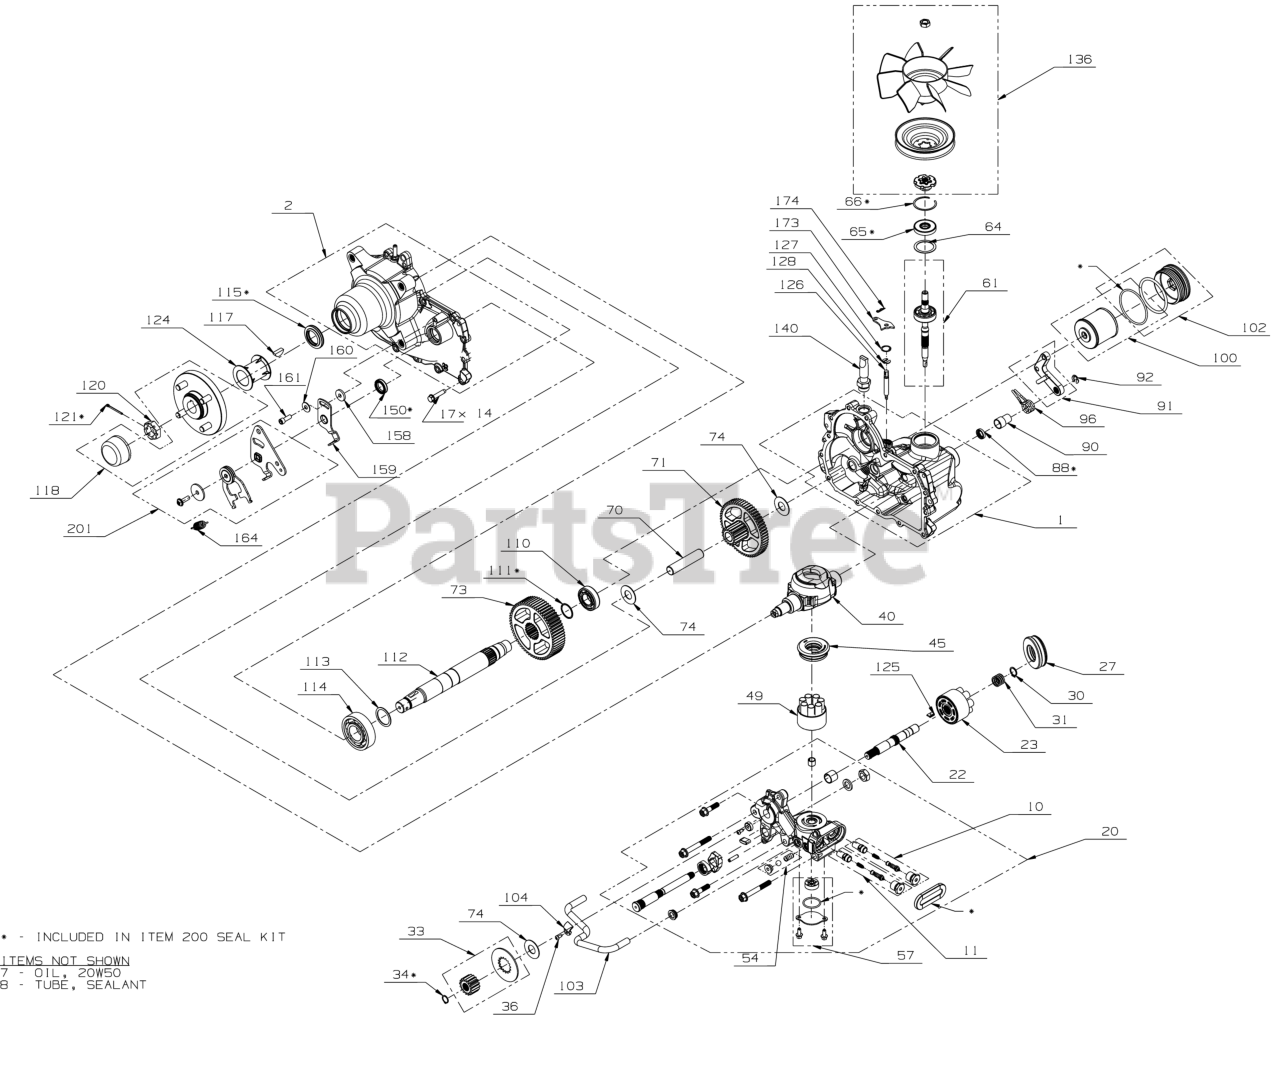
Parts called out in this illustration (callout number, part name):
1	MAIN HOUSING (RH) KIT
2	SIDE HOUSING (RH) KIT
8	SEALANT-HOUSING
10	SHOCK VALVE KIT
11	SHOCK VALVE KIT
17	HOUSING SCREW
20	CENTER SECTION (RH) KIT
22	MOTOR SHAFT
23	16CC CYLINDER BLOCK KIT
27	THRUST BEARING
30	RETAINING RING
31	SPRING-BLOCK
33	BRAKE ROTOR GEAR KIT
34	RETAINING RING
36	SCREW-SELF TAPPING
40	16CC MACHINED SWASHPLATE
45	THRUST BEARING
49	BLOCK KIT-CYLINDER
54	CHARGE RELIEF KIT
57	CHARGE PUMP KIT
61	INPUT SHAFT KIT
65	LIP SEAL
66	INTERNAL RETAINING RING 1.875
70	JACK SHAFT .78 X 3.63
71	GEARS KIT
74	FLAT WASHER .80 X 1.70 X .05
88	BRAKE SEAL
90	SPRING SPACER
91	RH BRAKE KIT
92	RETAINING RING
96	TORSION SPRING
100	FILTER KIT
102	FILTER CAP KIT
103	FILTER TUBE-RH
104	TUBE CLAMP
110	BALL BEARING
111	RETAINING RING 1.25
112	AXLE SHAFT
113	FLAT WASHER 1.40 X 1.75 X .05
114	BALL BEARING 35 X 80 X 21
115	LIP SEAL 1.375 X 2.062 X .250
117	WOODRUFF KEY 5/16 X 1
118	4 BOLT HUB KIT
120	SLOTTED 1-20 NUT
121	COTTER PIN 9/64 X 1.5
124	AXLE TUBE 1.40 X 2.22
125	BYPASS PLATE
126	BYPASS ROD
127	RETAINING RING
128	RETAINING RING
136	FAN/PULLEY KIT
140	STRAIGHT FITTING 7/8 SAE
150	LIP SEAL 22 X 32 X 7 TC
158	SPACER .32 x 1.005 x .179
159	ARM-NEUTRAL (RH)
160	FLAT WASHER
161	SCREWS KIT-RTN
164	EXTENSION SPRING
173	BYPASS ARM
174	HAIRPIN COTTER PIN
201	RETURN KIT-NEUTRAL (RH) ZT2800 RZT
